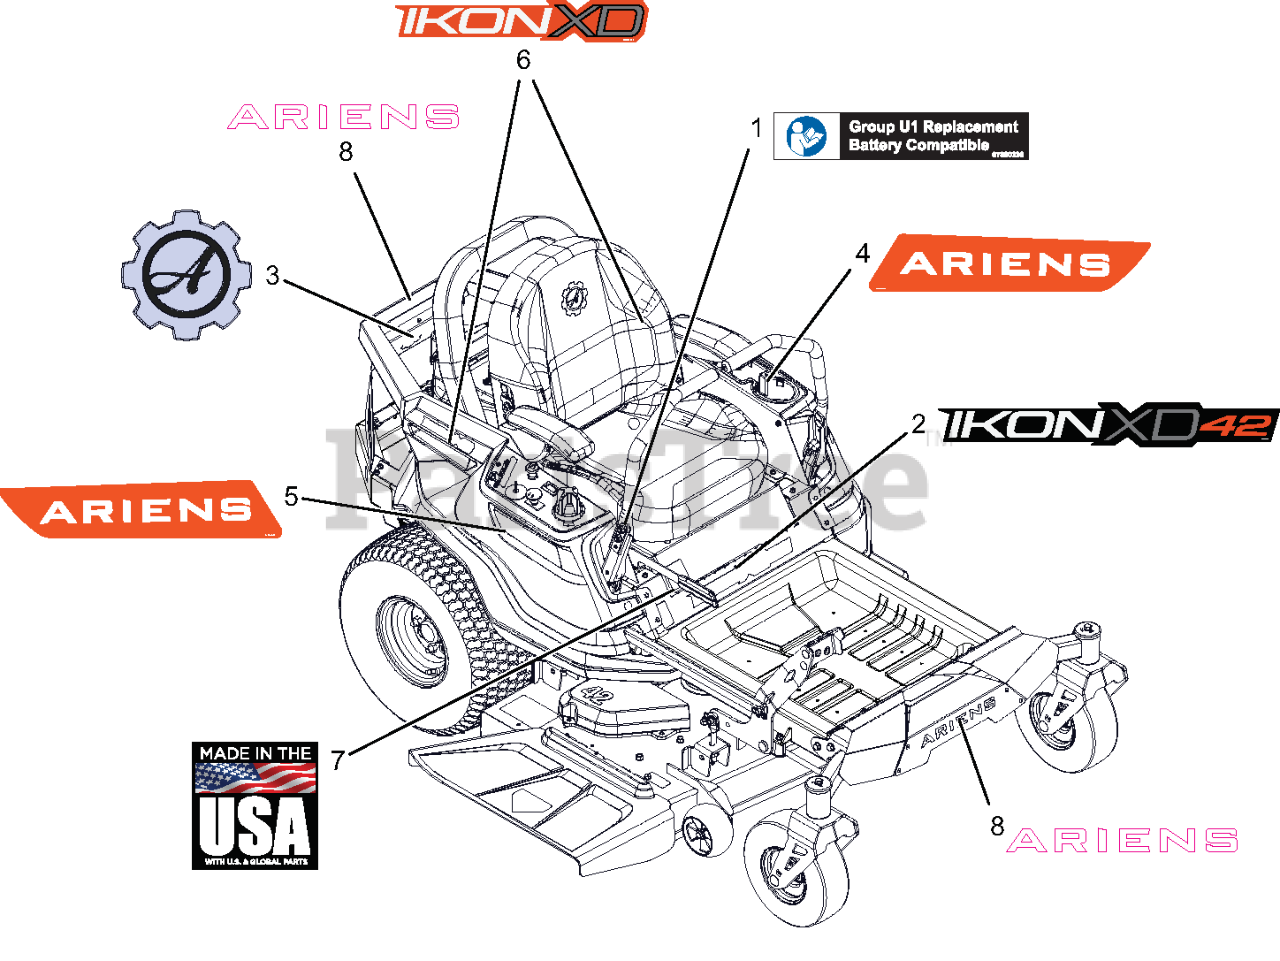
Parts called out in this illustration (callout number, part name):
1	DECAL, U1 BATTERY REPLACEMENT
2	DECAL, IKON-XD 42"
3	DECAL, ARIENS-GEAR BADGE -THK
4	DECAL, FENDER LH
5	DECAL, FENDER RH
6	DECAL, IKON-XD
7	DECAL, MADE IN USA
8	DECAL - ARIENS 9.625"
